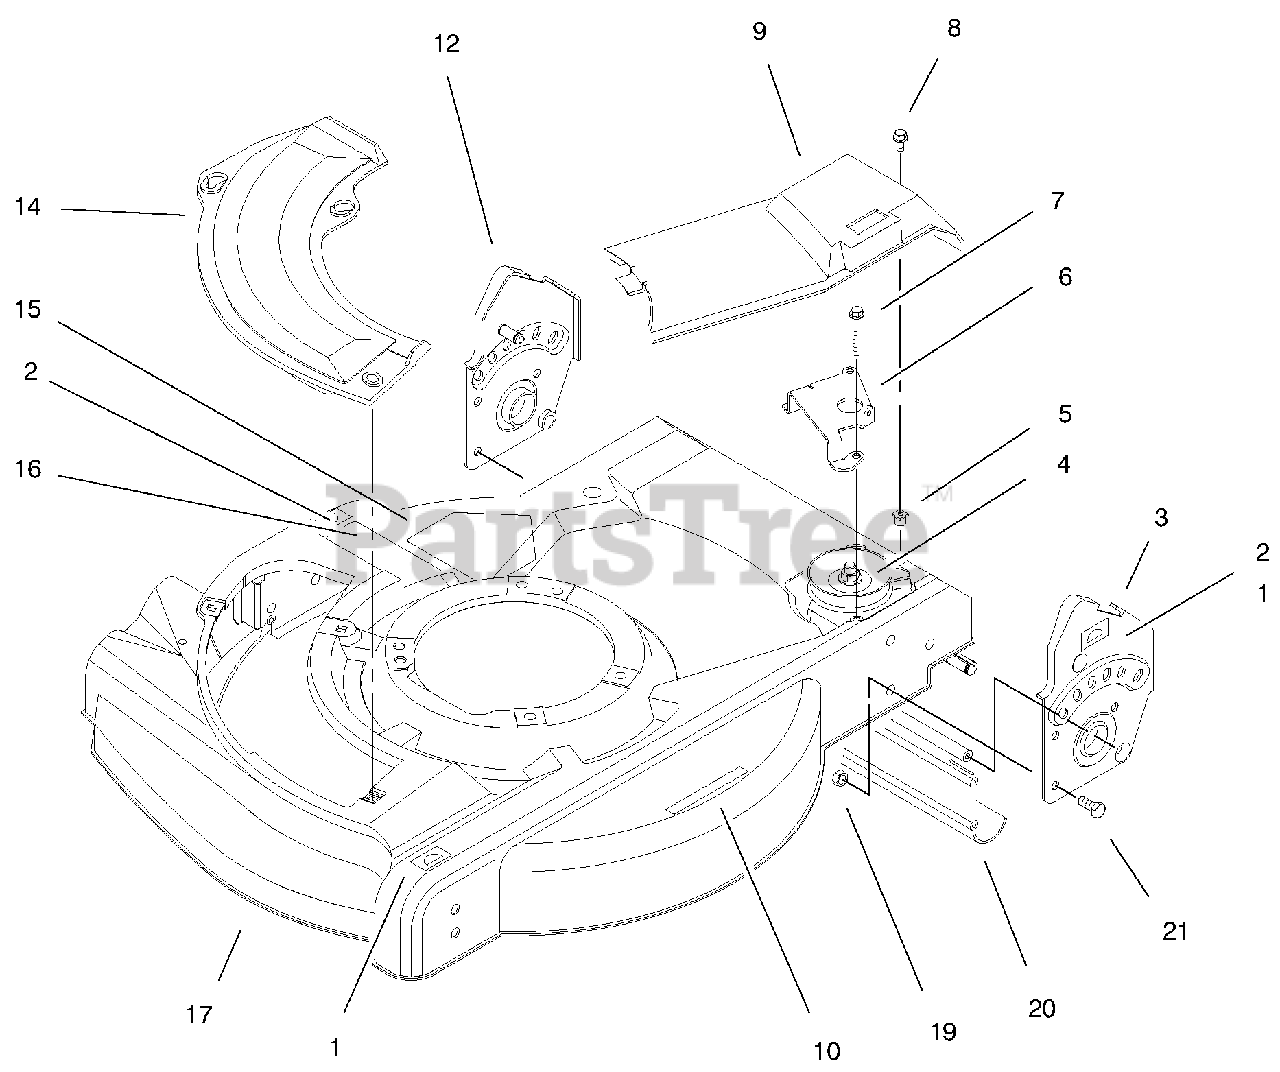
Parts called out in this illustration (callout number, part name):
1	Decal-H.O.C.
2	Decal-H.O.C.
3	Bracket-Handle L.H.
4	Gear Case Assembly
5	Grommet
6	Guide-Transmission
7	Screw-Hex Hd.
8	Screw-Phillips Hd.
9	Cover-Drive
10	Decal-Warning
12	Bracket-Handle R.H.
14	Plate-Cover
15	Decal-Danger
16	Decal-Discharge
17	Housing Assembly
19	Nut-Lock
20	Shield-Trailing
21	Screw-Hex Hd. Cap
